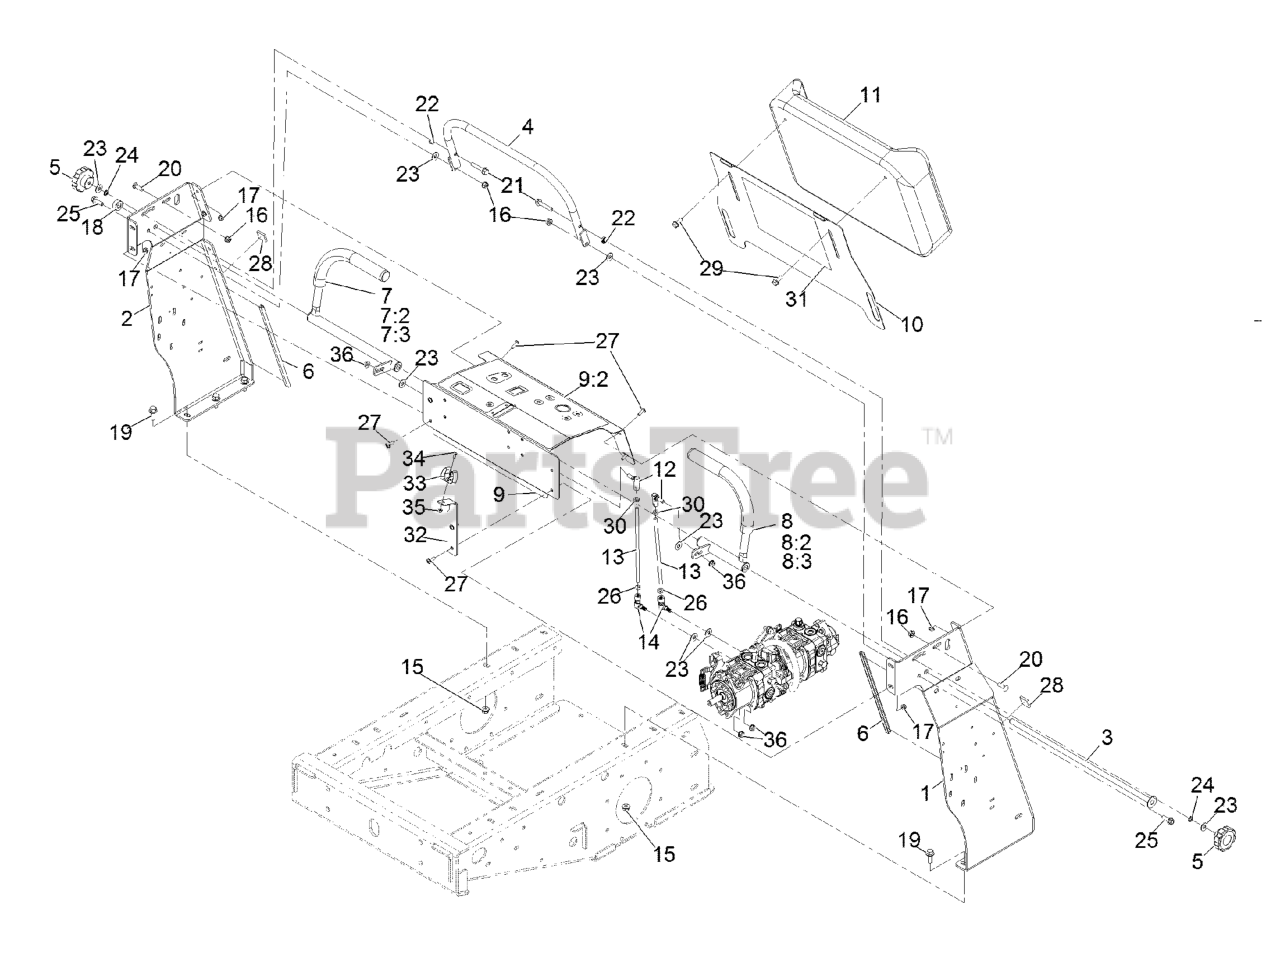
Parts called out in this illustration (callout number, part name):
1	Upright-Tower, Lt
2	Upright-Tower, Rt
3	Rod-Pivot, Joy Stick
4	Bar-Speed
5	KNOB-FLUTED
6	STRIP-TRIM, 12.0"
7	Stick-Joy, Rt
7:2	GRIP-CONTROL, MOTION
7:3	BUSHING-FLANGE
8	Stick-Joy, Lt
8:2	GRIP-CONTROL, MOTION
8:3	BUSHING-FLANGE
9	Panel-Control
9:2	DECAL-CONTROL PANEL
10	PLATE, KNEE PAD
11	Pad-Knee, Z-Spray/Z-Plug
12	Balljoint-SS
13	ROD-CONTROL, MOTION
14	Ball Joint-Quick Disconnect, SS
15	Nut-Hex Flange
16	Nut-Hex Flange
17	Nut-Hex Flange
19	SCREW-HHF
20	Bolt,Carriage,5/16-18X1,ST/ST 18-8
21	Screw-HHF
22	Nut,Hex Flange,5/16-18,Sst, Rie2006
23	FLAT WASHER, 5/16 NOM,ST
24	Washer-Lock
25	SCREW-HHF
26	Nut-Hex
27	Screw-Hsbhf
29	SCREW-HHF
30	Nut-Hex
31	DECAL-SPRAY CHART
32	Mount-Gun
33	Holder-Tool, Clip
34	Screw-HSBH
35	Nut-Hex Flange
36	Nut-HHF
